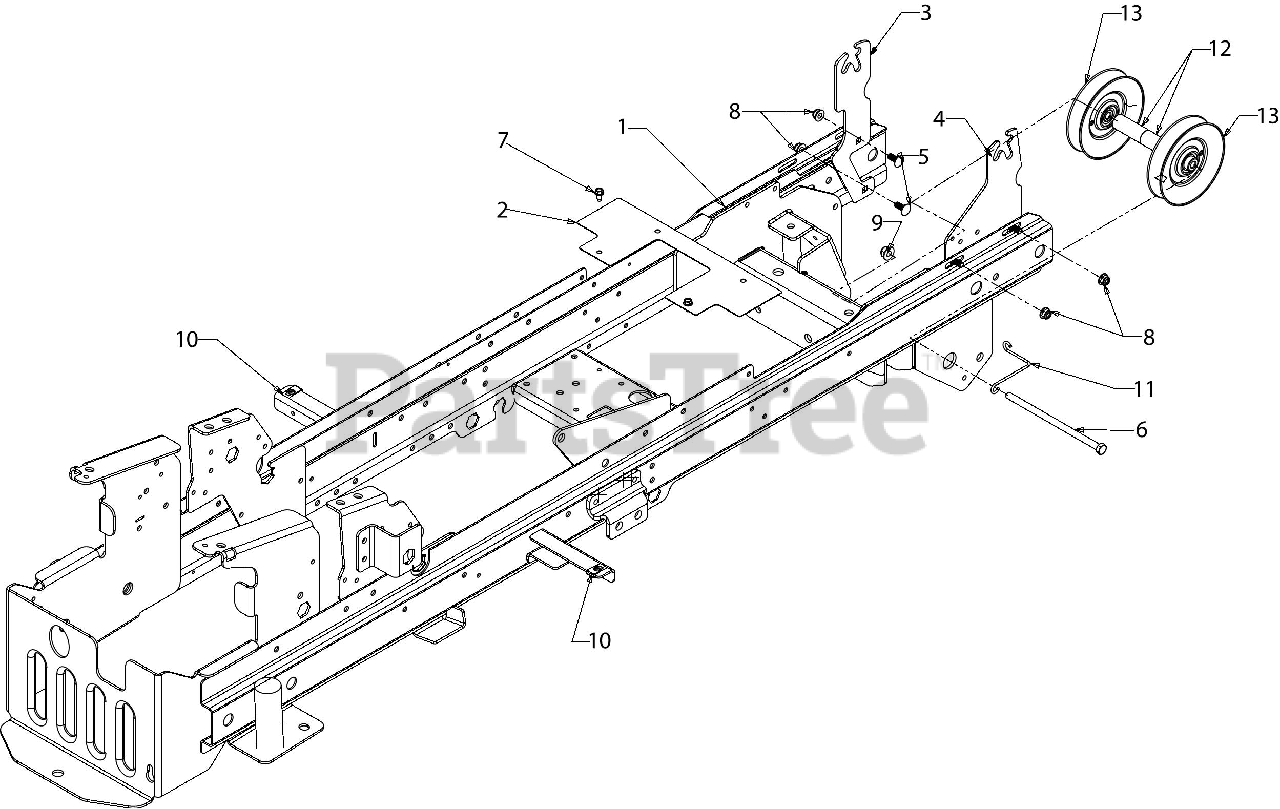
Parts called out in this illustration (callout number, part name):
3	HOOD PIVOT BRACKET (LH)
5	CARRIAGE BOLT 5/16-18 x .75
6	SCREW 3/8-16 x 7.25 GR5
7	SCREW 1/4-20 X.500
8	FLANGE LOCK NUT 5/16-18
10	U-NUT
11	BELT GUIDE
12	SPACER .41 x .875 x 2.19
13	IDLER PULLEY 5.06
